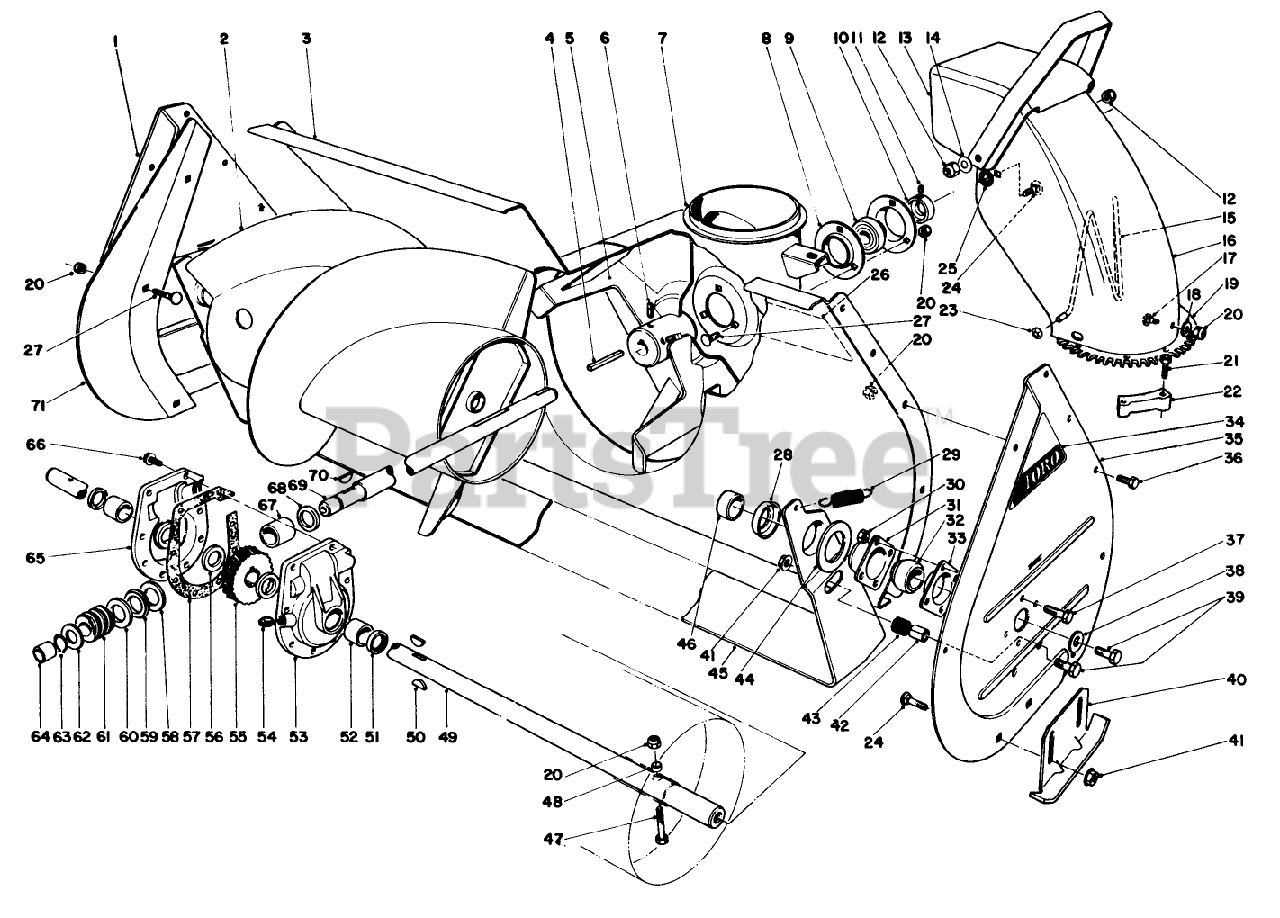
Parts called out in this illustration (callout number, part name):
1	RH AUGER SIDE PLT R
2	RH AUGER ASM - 32"
3	Auger Housing
5	IMPELLER ASM
6	SCREW-SET, SQH
7	CHUTE RING
8	BRG FLANGE
9	BALL BRG W/COLLAR
10	EXT LOCKING COLLAR
11	SCREW-HSH
12	NUT-LOCK, CONE
13	Deflector
14	WASHER-BELLEVILLE
15	WIRE-CHUTE
16	Upper Chute
17	SCREW-CARR
18	WASHER-PLAIN
19	Screw
20	NUT-LOCK, NI
21	SCREW-SPECIAL
22	RETAINER-CHUTE
23	NUT-PUSH
24	SCREW-CARR
25	WASHER-RUBBER
26	Decal-Warning
27	BOLT-CARR
28	Positioner-Scraper
29	SPRING-TENSION
30	NUT-LOCK, CONE
31	BEARING-FLANGE, FRONT
32	BEARING
33	BEARING-FLANGE, REAR
34	AUGER SIDE PLT DECAL
35	LH AUGER SIDE PLT R
36	SCREW-HH
37	SCREW-HH
38	WASHER
39	SCREW-HH
40	AUGER SKID WA R
41	NUT-HF
42	SCRAPER STOP SPACER
43	SCRAPER STOP CUSHION
44	SCRAPER BLADE SPACER
45	SCRAPER BLADE 32" R
46	AUGER SPACER
47	Auger Bolt
48	SPACER-HUB, AUGER
49	32 AUGER SHAFT
50	KEY-WOODRUFF
51	SEAL-OIL
52	BUSHING
53	Gear Case Bushing Assy.-L.H. (Incl. Ref. #51, 52)
54	PLUG-PIPE, SQH
55	GEAR-WORM, 27T
56	WASHER-THRUST
57	asket
58	WASHER-THRUST
59	BEARING-THRUST
60	THRUST-WASHER
62	WASHER-THRUST
63	Ring-Snap
64	BUSHING
65	Gear Case Bushing Assy.-R.H. (Incl. Ref. #51, 52)
66	SCREW-TAPTITE
67	BUSHING-SPECIAL
68	RING-QUAD
69	SHAFT-IMPELLER
70	KEY-WOODRUFF
71	Auger Housing Extension R.H.
